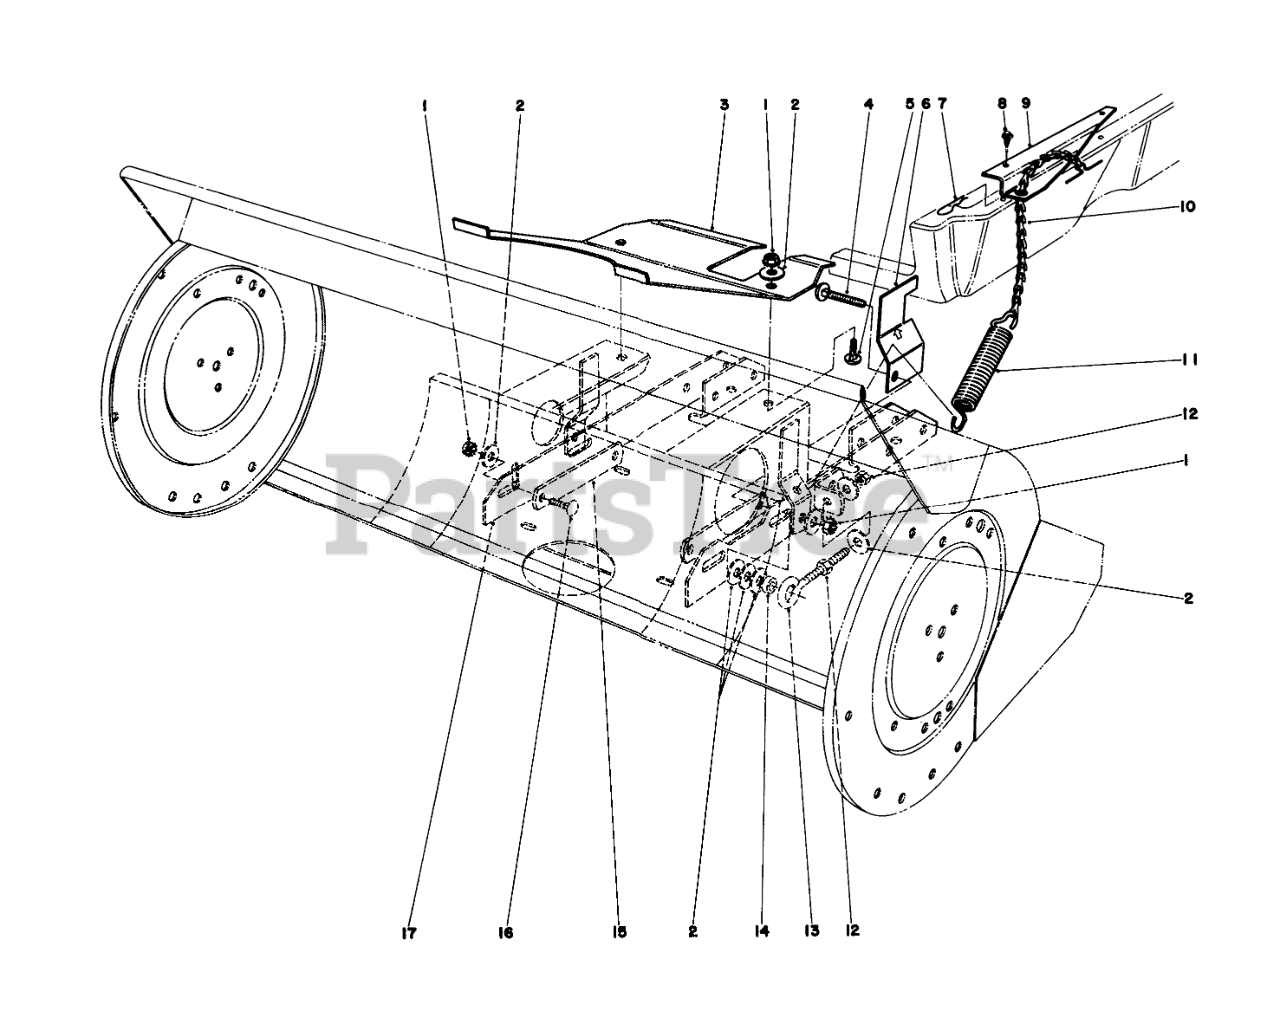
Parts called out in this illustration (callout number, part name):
1	NUT-KEPS
2	WASHER-FLAT
3	Guard-Drive Pulley
4	SCREW-CARR
5	SCREW-CARR
6	Bracket-Belt Adjust Guide
7	PIN-HAIR
8	SCREW-HWHTF
9	Plate-Lift Spring Anchor
10	CHAIN & TOGGLE ASM
11	IDLER ARM SPRING
12	NUT-HEX
13	Eye Bolt
14	Spacer
15	Strap-Header Channel
16	BOLT-CARR
17	Pivot Bracket
